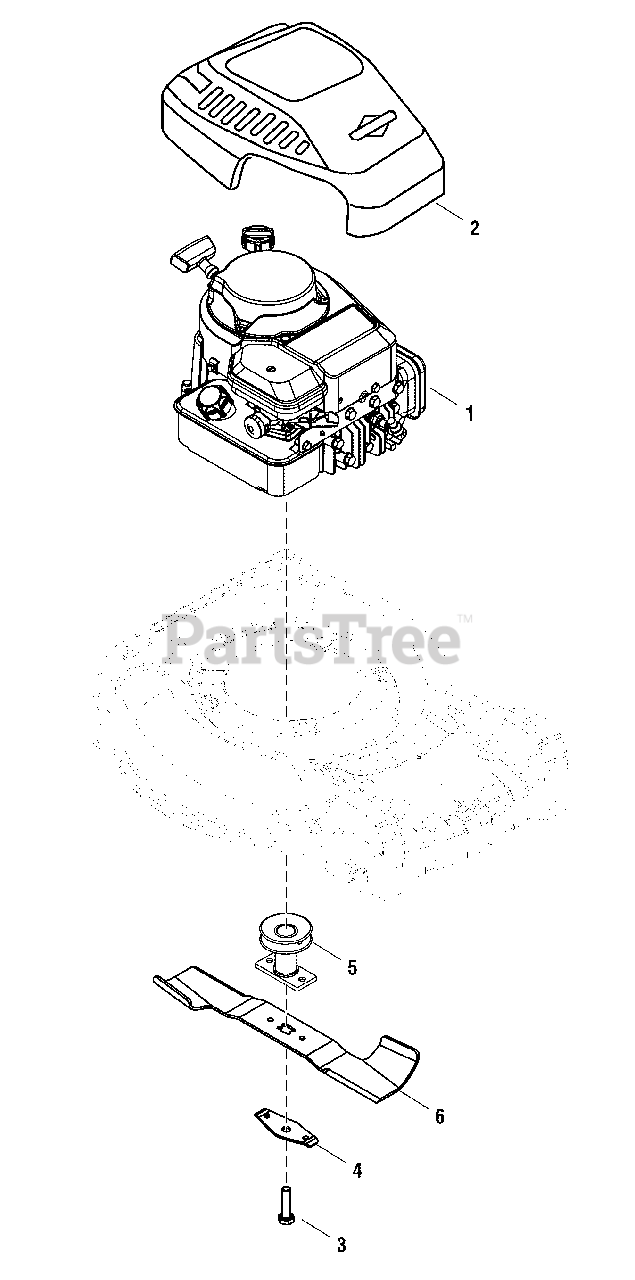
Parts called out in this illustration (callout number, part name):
1	* ENGINE, Briggs & Stratton, 09P602-0004-H1
3	SCREW Hex, 3/8-24 x 1-1/2
4	SUPPORT, Blade Bell
5	BLADE ADAPTER
